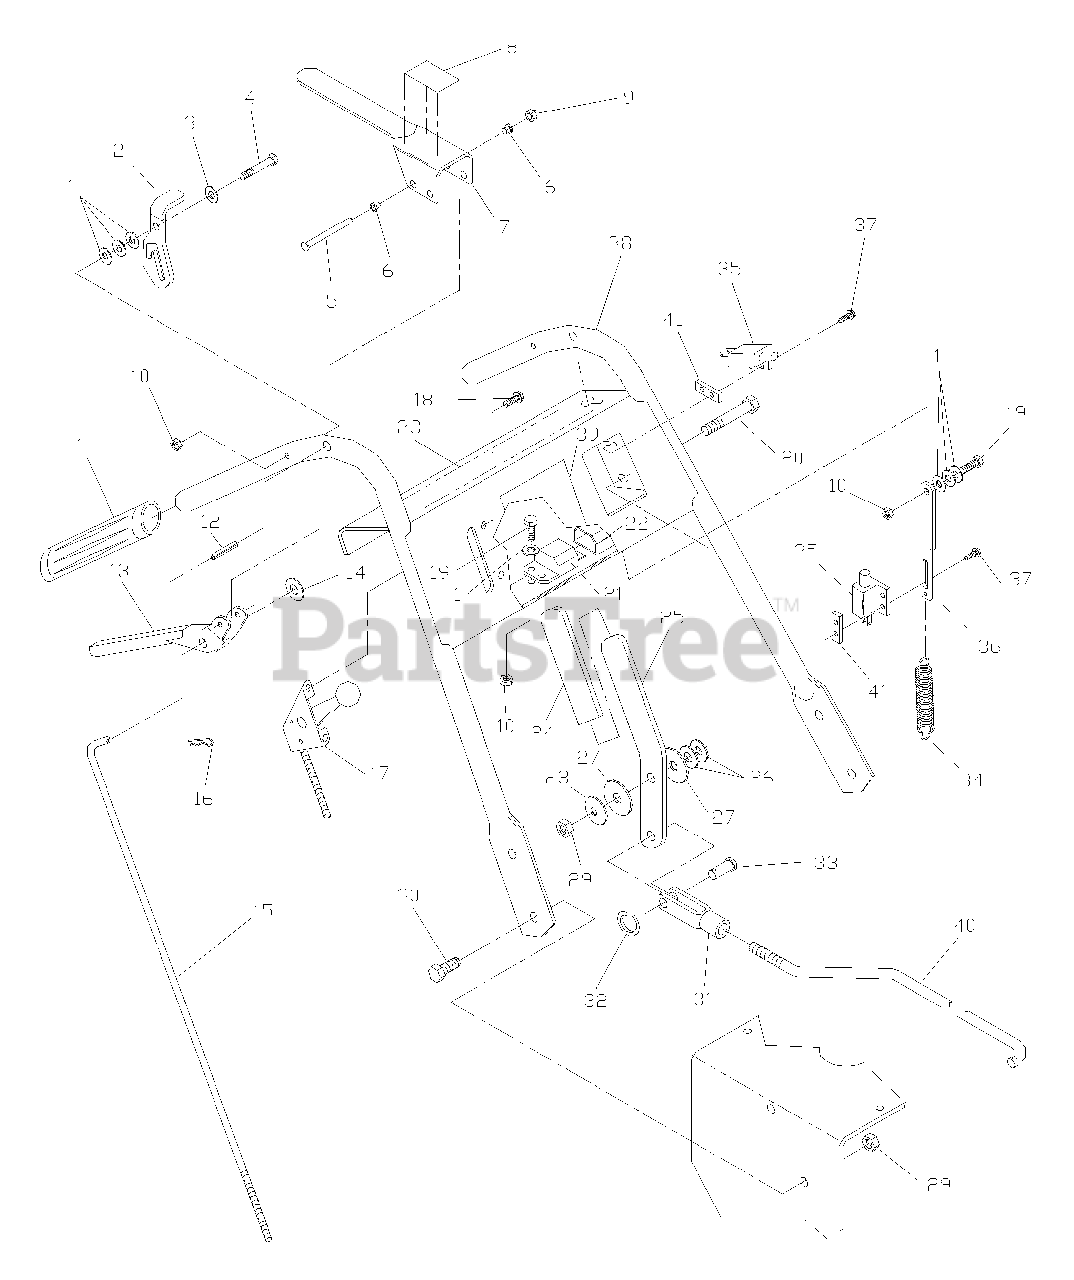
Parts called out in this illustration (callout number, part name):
1	1/4SAE FLAT WASHER
2	LATCH, LT. THUMB W/GRIP
2	LATCH, RT.THUMB W/GRIP
3	WASHER, WAVE SPRING
4	HCS 1/4C X 1 3/4
5	PIN, CLEVIS
7	LEVER, O.P. W/GRIP
8	DECAL, THUMB LATCH
10	1/4C PREV. TORQUE NUT
11	GRIP HANDLE
12	ROLL PIN 5/16 X 1 1/8
13	LEVER, MOLDED DRIVE
14	5/16 FLAT WASHER
15	TRACTION ROD
16	COTTER, HAIRPIN #2
17	THROTTLE CONTROL W/BALL
18	HWST 1/4C X 3/8
19	HCS 1/4C X 3/4
20	HCS 3/8C X 1 1/2
22	HANDLE HARNESS
23	DECAL, OPERATION
26	3/8 FLAT WASHER
27	FIBER WASHER
28	CONE WASHER
29	3/8C TORQUE NUT
30	HCS 3/8C X 1
32	RETAINER, RING
33	CLEVIS PIN
36	O.P. LINKAGE
37	SCREW 10-24 X 5/8
38	UPPER HANDLE W/DECALS
39	DECAL, OPERATION
41	TAPPED PLATE
